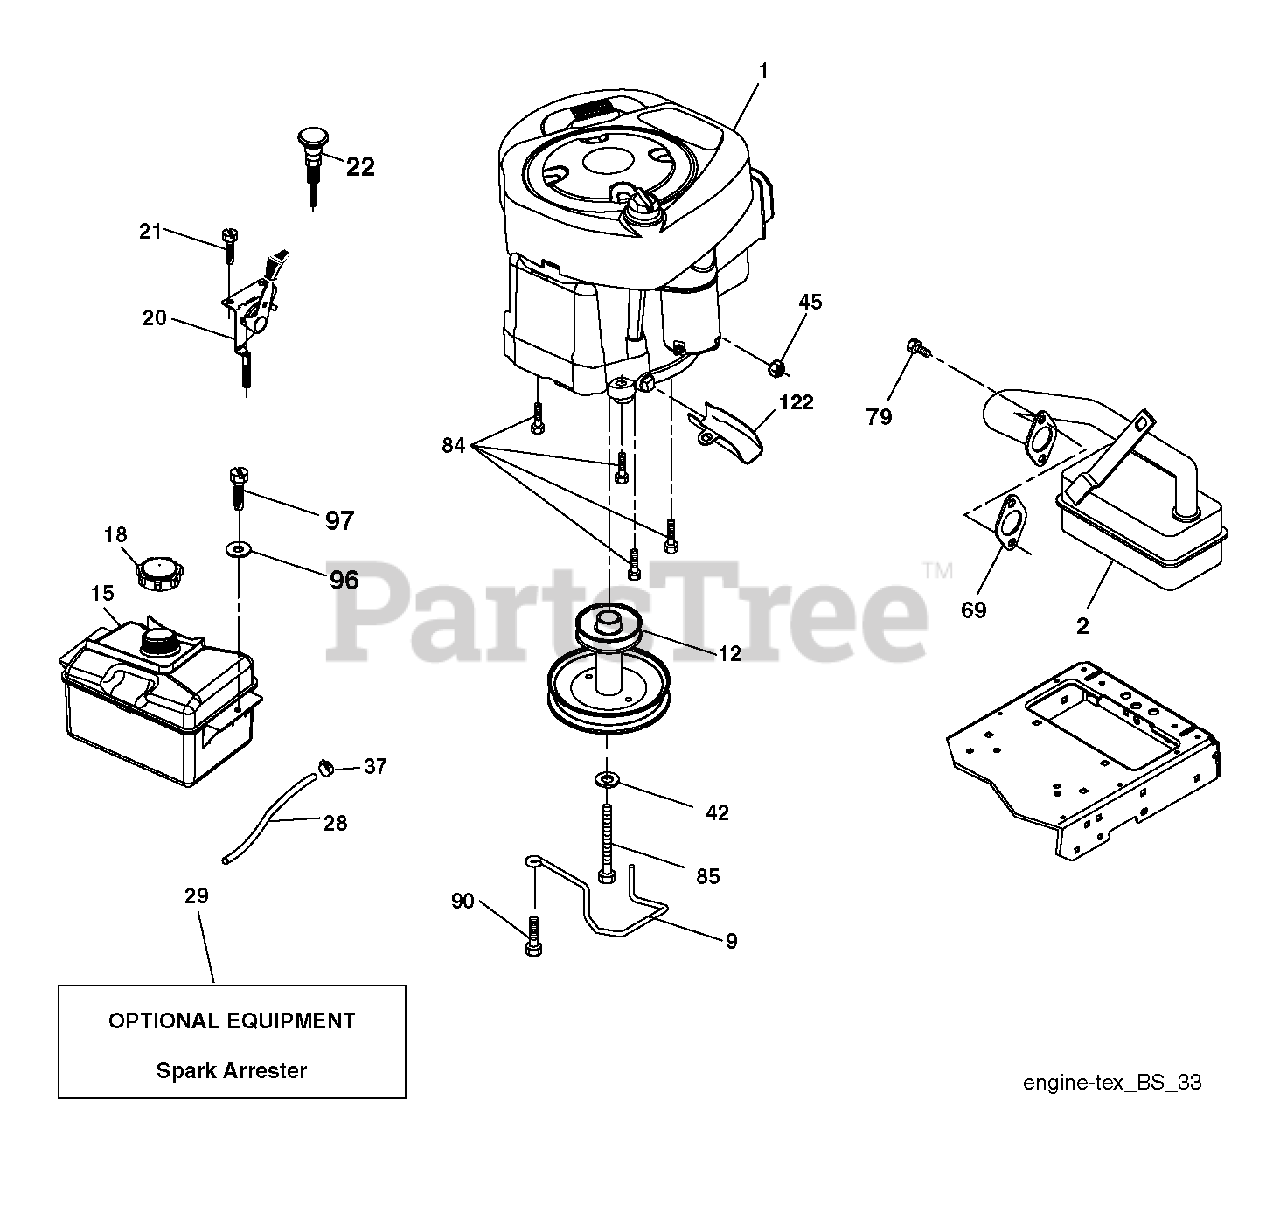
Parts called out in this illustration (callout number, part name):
9	KEEPER.BELT.ENGINE.4.2
12	PULLY ENGINE
15	TANK FUEL FRT 1.5 GAL
18	CAP ASM.FUEL.2.25"FR.
20	CONTROL.THCK.COBRA.BS
21	SCREW.#10 X 0.750.BOS THREAD
22	CONTROL.CHOKE.ERGO.1CYL.30".YE
28	LINE.FUEL.20
29	ARRESTER SPARK (OPTIONAL)
42	LOCKWASHER
45	NUT
69	REPL BY 532 27 22-93
79	SCREW.SOCKET HD.5/16-1
85	BOLT HEX 7/16-20X4-1/4"
90	SCREW 3/8-16X1
96	WASHER
97	SCREW HEXWSHR 1/4-20X3/4
122	EXTENSION DRAIN OIL
